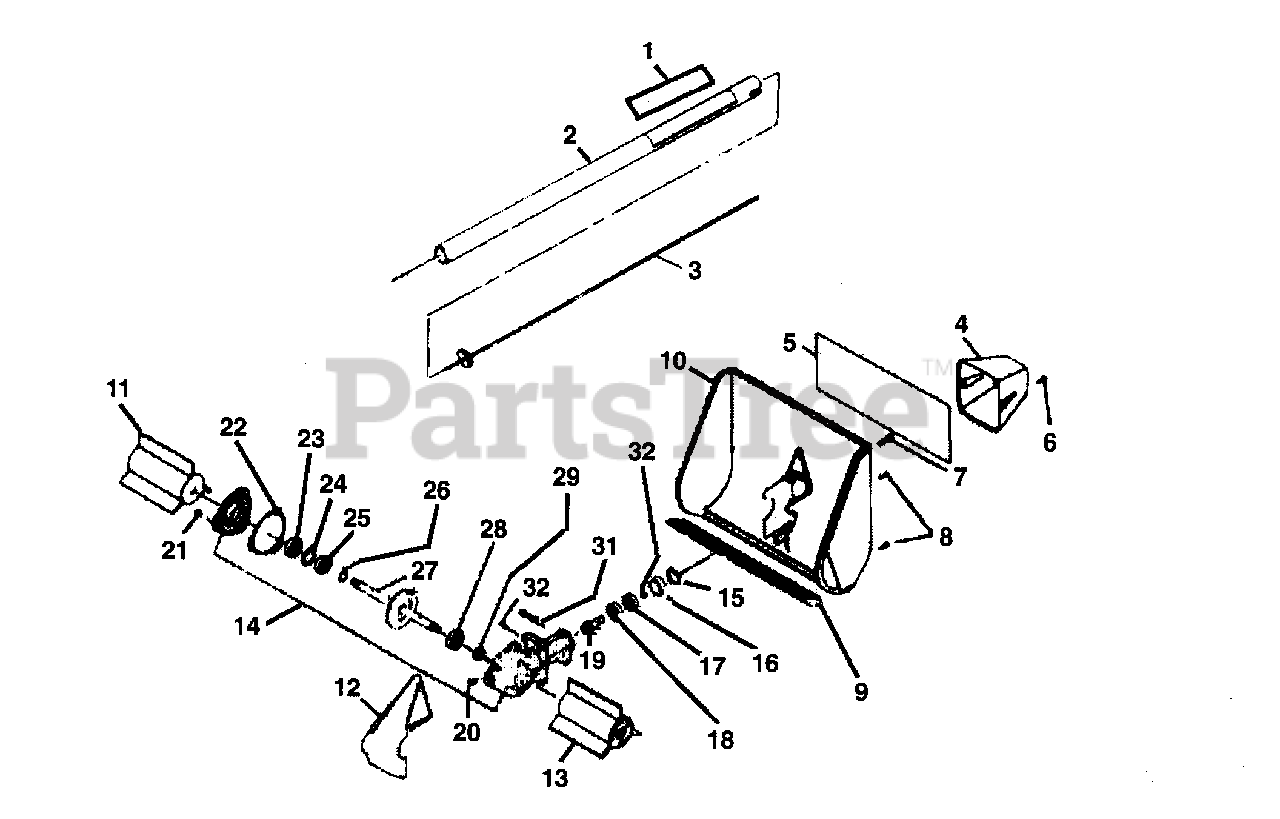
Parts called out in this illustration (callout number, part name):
1	LABEL, WARNING
2	TUBE ASSY.
3	FLEX CABLE
6	SCREW
7	SCREW
8	SCREW
9	SCRAPER BAR
11	ROTOR L.H.
13	ROTOR R.H.
14	GEAR CASE HSG.
15	SNAP RING
18	BEARING
19	PINION GEAR
20	SCREW
21	SCREW
22	GASKET GEARBOX
27	SHAFT & GEAR
30	SCREW
32	SNAP RING
